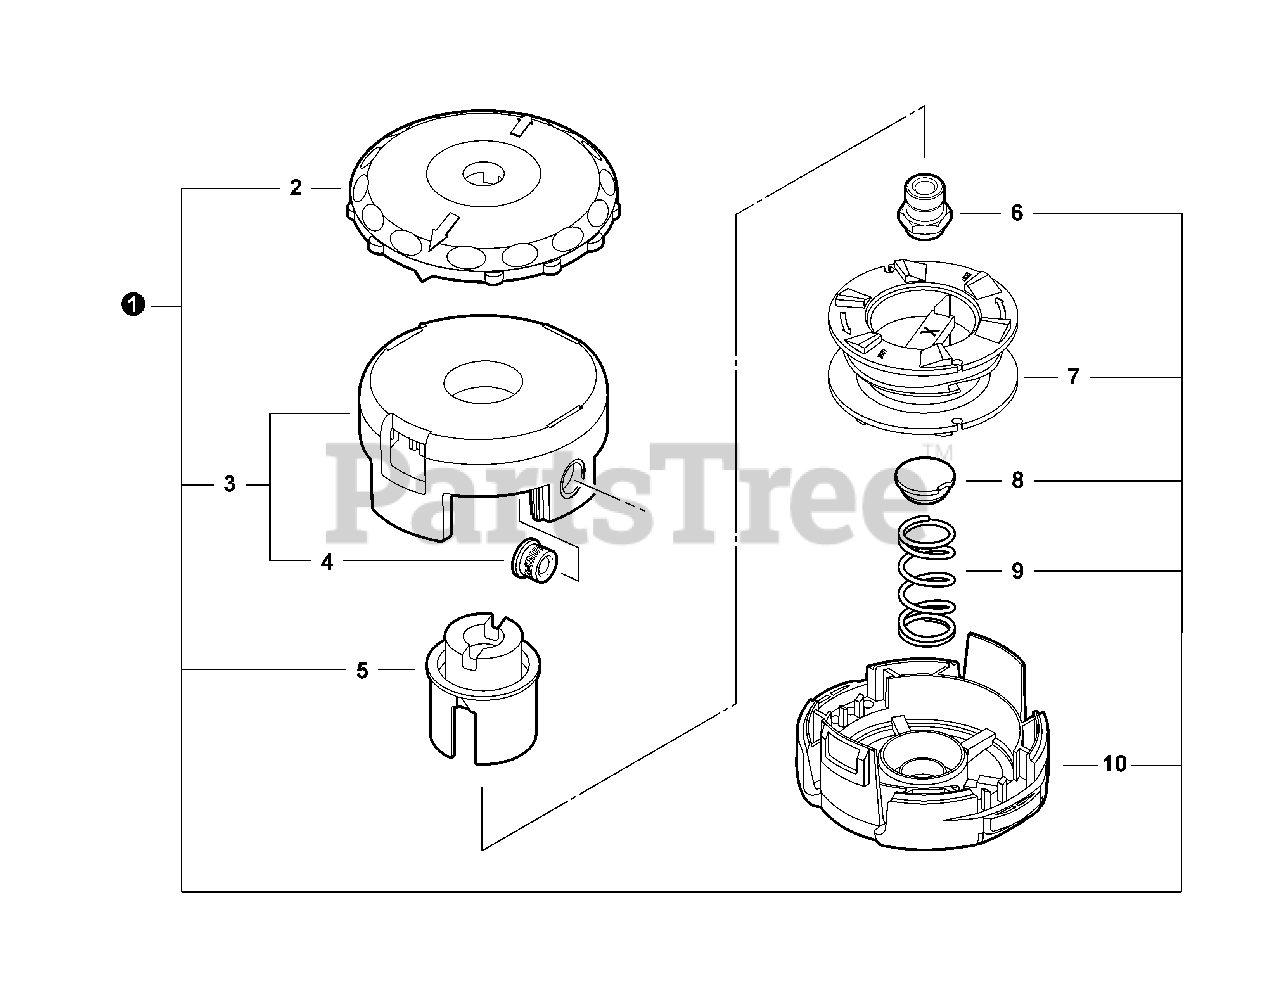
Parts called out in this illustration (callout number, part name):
1	TRIMMER HEAD, SPEED-FEED® 400
3	HOUSING ASSY, SPOOL
5	HUB (LH) BLACK
6	BUSHING M10×1.25 LH GOLD
8	CAP, SPRING
9	SPRING, GOLD
10	COVER, SPOOL
